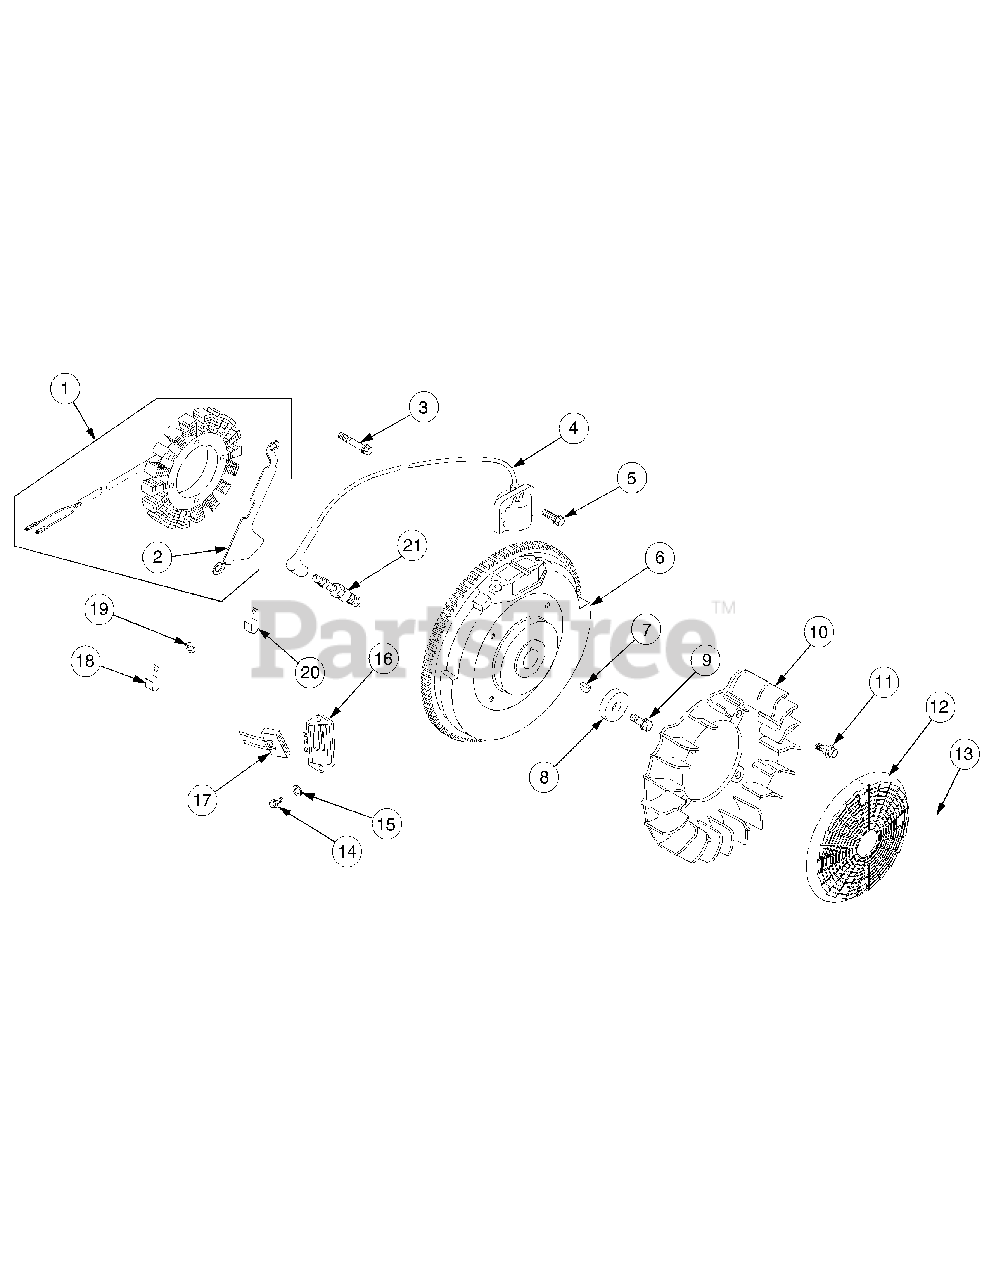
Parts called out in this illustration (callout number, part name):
1	Stator Kit, 15 Amp (Incl. Ref #2)
2	Bracket, Stator Wire
3	Screw, Stator Mtg. M5 x .8 x 25
4	Module, Ignition
5	Screw, Module M5 x .8 x 20
6	Flywheel Assembly
8	Washer, Flywheel Mtg. Screw
9	Screw, Flywheel Mtg, M10x1.5 x 46
10	Fan
11	Bolt, Shoulder
12	Screen, Grass
13	Retainer
14	Screw Phillips Hd., #11-16 x .875
15	Washer, Plain
16	Regulator - Rectifier
17	Connector, Regulator-Rectifier
18	Clip, Cable
19	Washer, Plain 1/4"
21	Spark Plug
